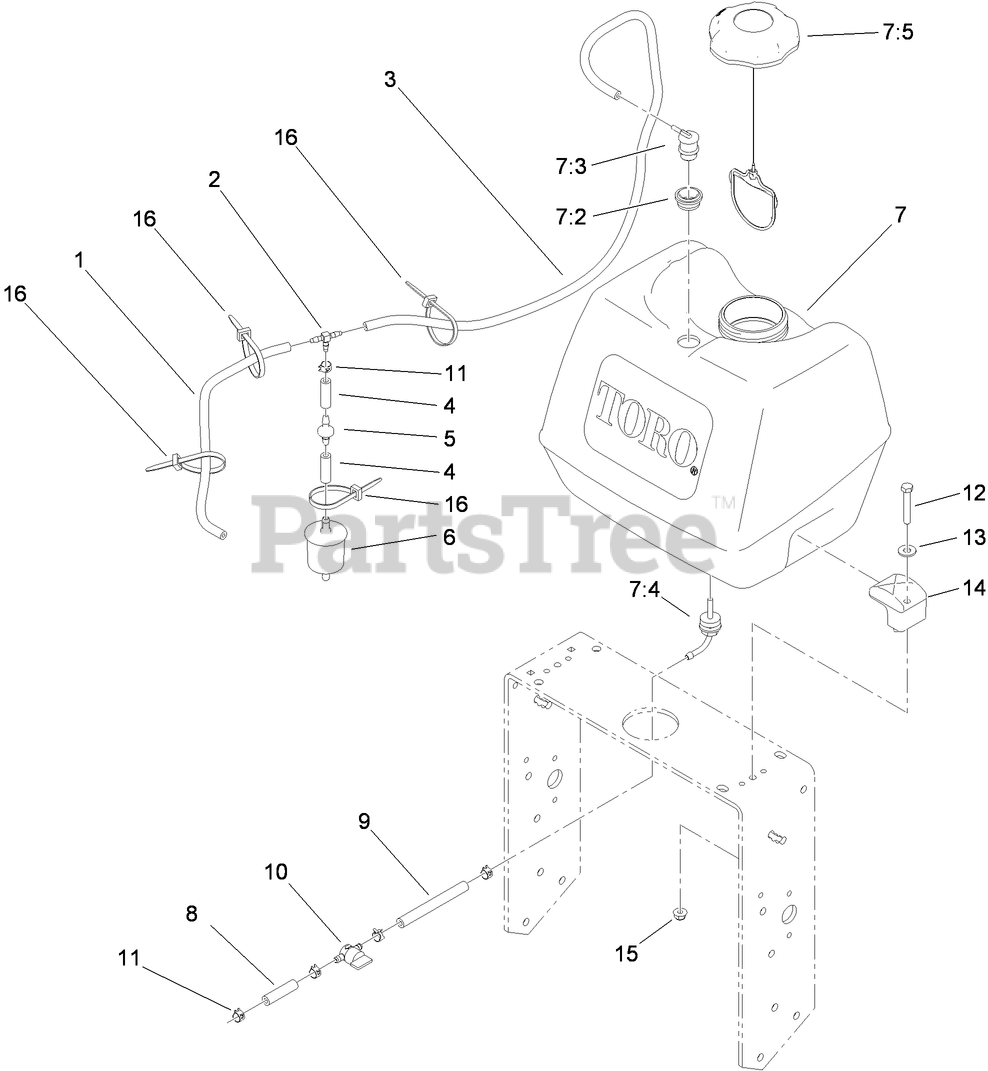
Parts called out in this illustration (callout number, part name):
1	HOSE-FUEL
2	FITTING-TEE
3	HOSE-EMISSIONS
4	HOSE-FUEL
5	VALVE-CHECK, FUEL
6	FILTER-FUEL
7	FUEL TANK ASM
7:2	GROMMET-VALVE, ROLL-OVER
7:3	VALVE-ROLLOVER
7:4	FITTING-FUEL, BULKHEAD
7:5	CAP-FUEL, RATCHETING
8	HOSE-FUEL
9	HOSE-FUEL
10	VALVE-FUEL
11	CLAMP-HOSE
12	SCREW-HH
13	WASHER-FLAT
15	NUT-HF, NI
16	TIE-CABLE
